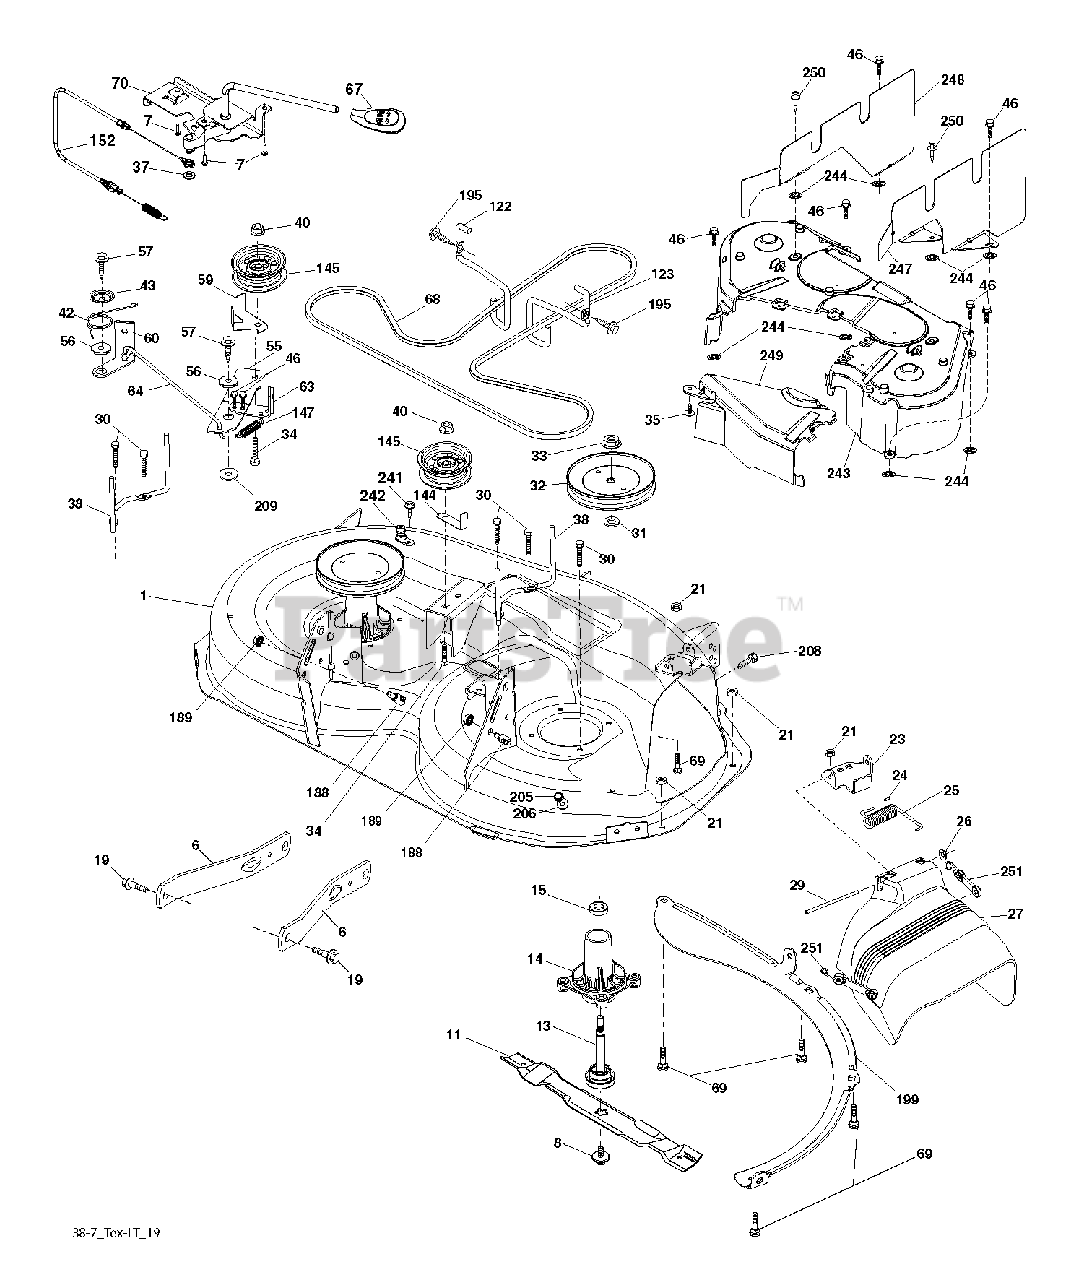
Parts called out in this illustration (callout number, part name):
6	ARM.SUSPENSION.MOWER.R
7	SCREW.#10 X 0.750.BOS THREAD
8	BOLT.WASHER.ASM.7/16-2
11	BLADE 38" PREMIUM
13	SHAFT.ASM.MDRL.N/GREASE.38
14	HOUSING MANDREL
19	BOLT.SHOULDER
21	LOCKNUT
23	BRKT.DEFLECTOR.38"2005+
24	CAP-SLEEVE LT
25	SPRING.TORSION.DEFLECT
26	NUT PUSH M
29	ROD.HINGE
30	SCREW, WASHER HEAD
31	WASHER.SPACER.MANDREL
32	PULLEY.MANDREL.5.0.PD.38"
33	NUT.FLANGE.LOCK.TOP
34	BOLT.3/8-16X1.50
35	FASTENER.XMAS.TREE
38	KEEPER BELT LH MANDREL
40	NUT LOCK FLG 3/8-16 UNC
42	SPRING.TORSION.BRAKE
43	SRPING.TORSION.RETAINE
46	SCREW.1/4-20X5/8
55	IDLER.ARM
56	SPACER.RETAINER
57	SCREW 3/8-16X1
59	GUARD, BELT
60	ARM BRAKE MOWER RH 38"
63	ARM BRAKE MOWER RH
64	LINK BRAKE
67	HANDLE.CLUTCH.CABLE.LT
69	BOLT
70	CLUTCH.ASM.MANUAL.LT.PRED
122	KEEPER BELT ENGINE LH
123	KEEPER BELT RH
144	KEEPER BELT
145	PULLEY.IDLER.48"PRIMARY
147	SPRING RETURN
152	CABLE.CLUTCH.MANUAL.
188	STUD.FASTNER.W/ANTI-ROTATE
189	NUT LOCK HEX FLANGE 5/16-18
195	SCREW, 3/8-16X3/4
199	BAFFLE VORTEX
205	SCREW
208	SCREW 3/8-16X1/2
209	WASHER 12/32X2X10GA
242	PORT.WASHOUT
244	PALNUT 1/4
